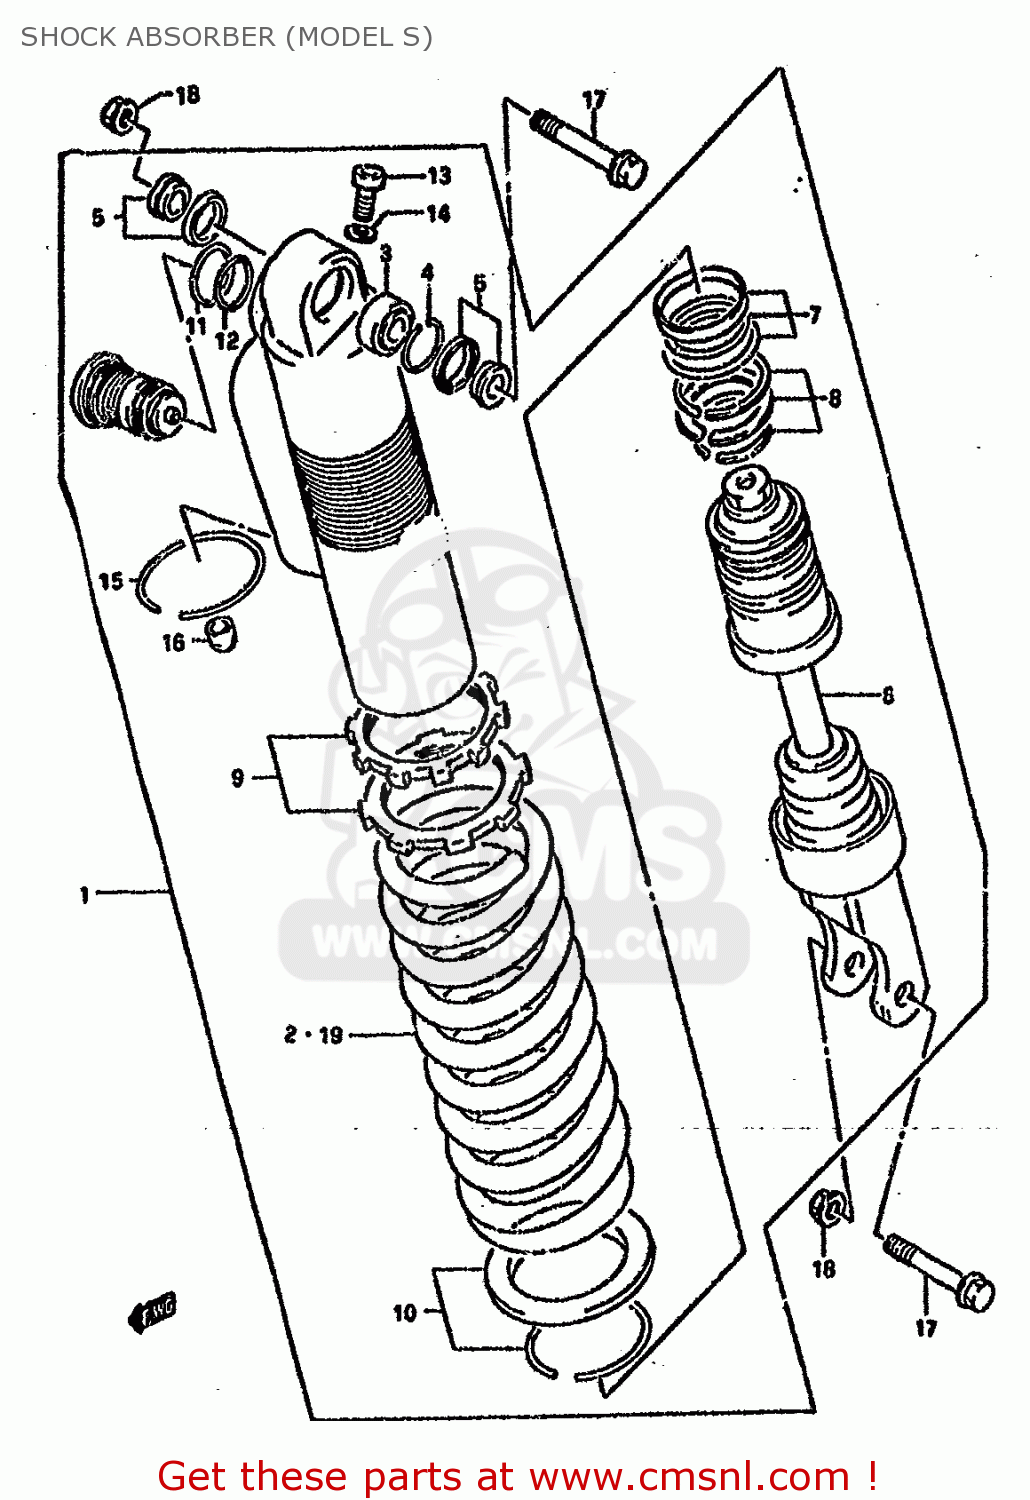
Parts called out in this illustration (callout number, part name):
1	ABSORBER ASSEMBLY,REAR SHOCK
2	SPRING
3	BEARING,RR CUSHION LEVER RR
4	RING,STOPPER
5	COLLAR SET,RR SHOCK ABSORBER
6	ROD,PISTON
7	O RINR SET
8	RING STOPPER SET,ABSORBER
9	ADJUSTER SET,SHOCK ABSORBER
10	SPRING SEAT SET,SHOCK ABSORBER
11	O RING
12	O RING,CTR BOLT UPR
13	BOLT,REAR SHOCK ABSORBER
14	GASKET,DRAIN,PLUG (NAS)
15	RING,STOPPER
16	CAP
17	BOLT,RR SHOCK ABSORBER
18	NUT
19	SPRING
21	CAP
22	BOLT,RR SHOCK ABSORBER
23	NUT
24	SPRING
